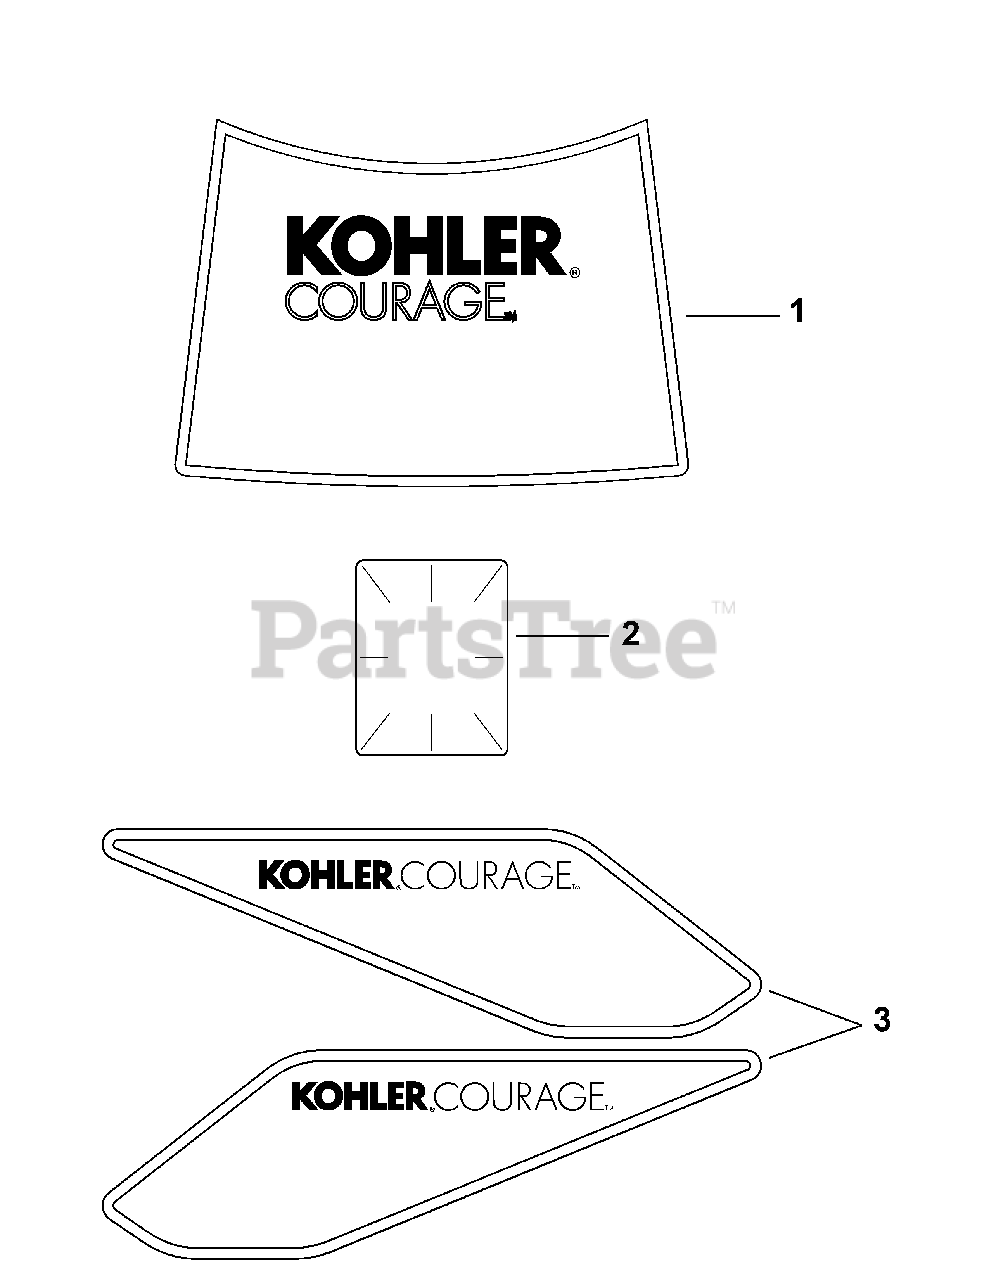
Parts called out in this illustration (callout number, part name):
1	27 HP Decal
2	Clear Laminate Decal
3	MTD/CUB Decal (2-pc Wing Set)
